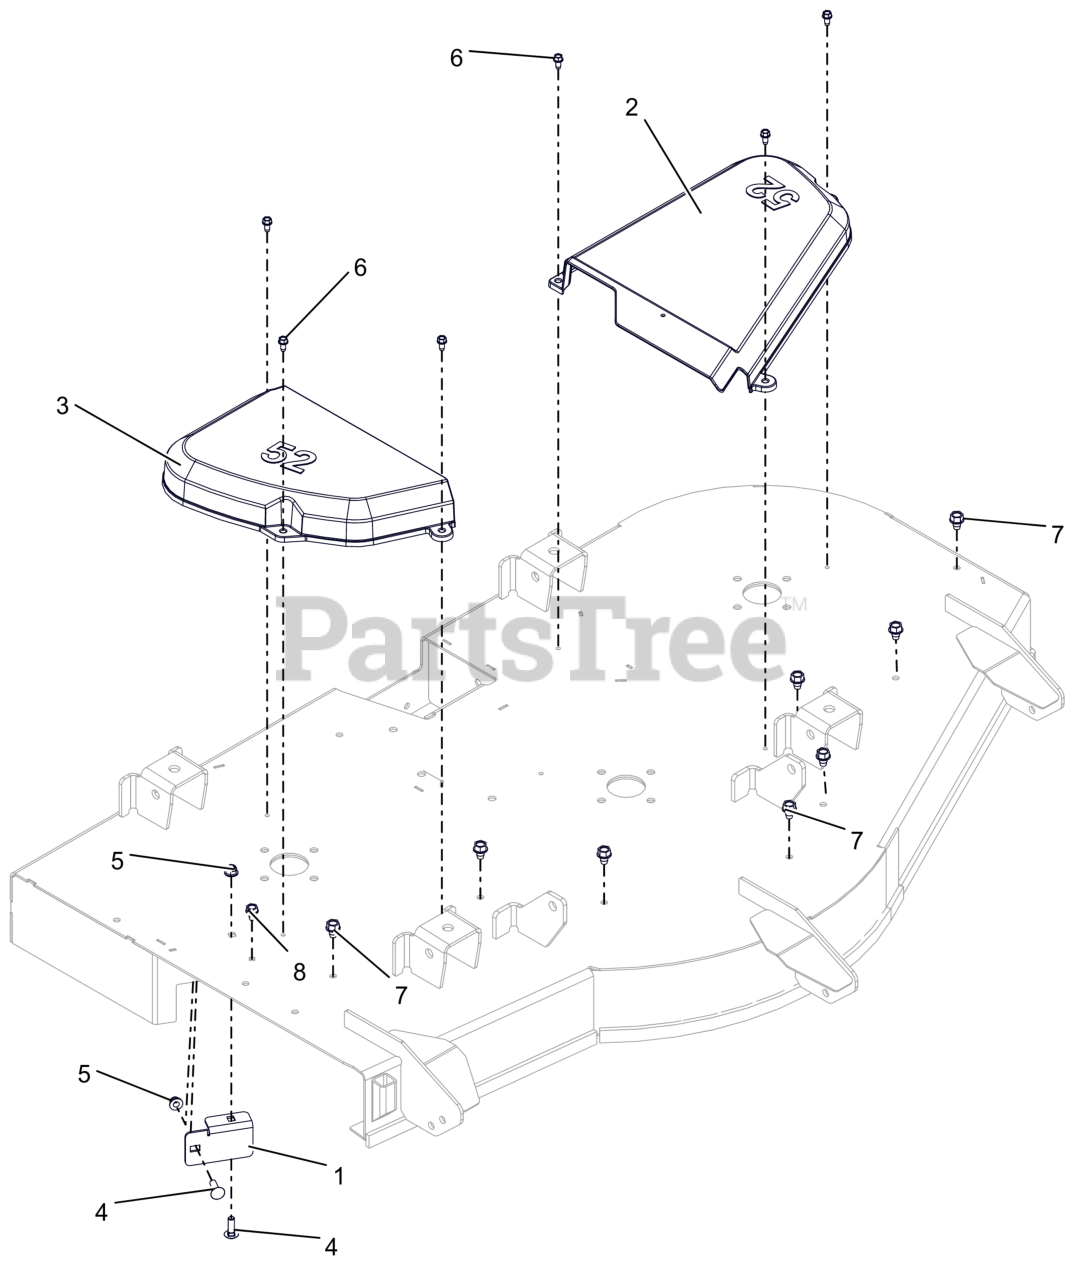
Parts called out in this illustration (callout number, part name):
1	STRIP, DEFLECTOR - 52"
2	COVER, BELT 52" LH
3	COVER, BELT 52" RIGHT
4	BLT,RHSN .31-18X1.00 G5 ZCC
5	NUT,LK-NYL-FLG .31-18 G5ZC120
6	SCR-TAP .25-20X.50 HWH ZCC
7	SCR,TAP .375-16X.50 HWH TR ZCC
8	SCR,TAP .312-18X.50 HWH TR ZCC
